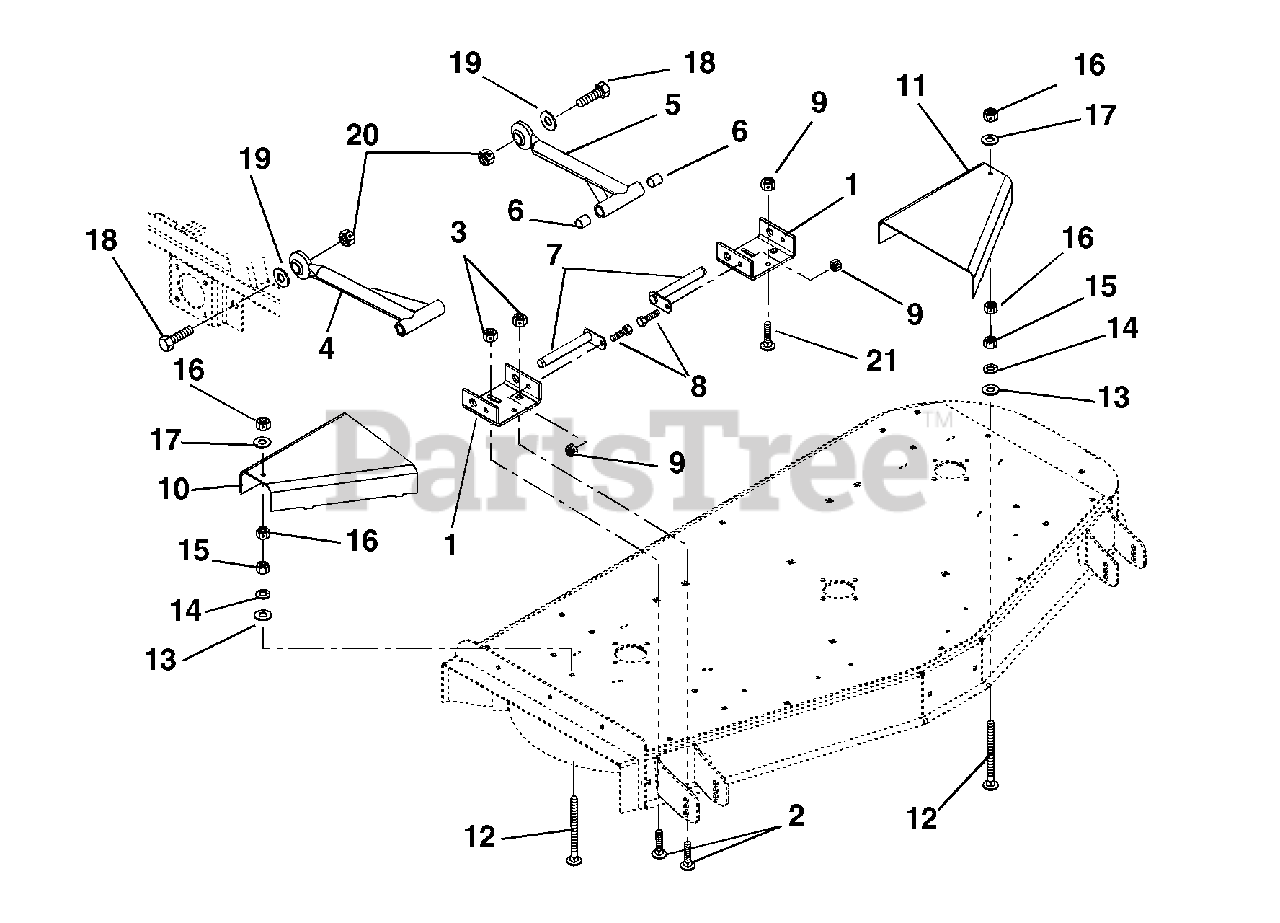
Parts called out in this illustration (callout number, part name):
1	Bracket, Mower Mounting (Rear)
2	Bolt-Round Head Square Neck .50-13 x 1.00 Grade 2
3	Nut-Locking-Center .50-13
4	Assembly, Mower Mounting Arm
5	Weldment-Mower Mounting Arm
6	Bearing .75 x .875 x 1.00
7	Weldment, Mower Mounting Pin
8	Bolt-Hex .38-16 x .75 Grade 5
9	Nut-Locking-Center .38-16
10	Guard, Pulley Right Hand
11	Guard, Pulley Left Hand
12	Bolt-Round Head Square Neck .31-18 x 3.50
13	Washer-Flat-Steel .344 x .688 x .065
14	Washer-Locking .31 x .078
15	Nut-Hex .31-18
16	Nut-Locking-Center .31-18
17	Washer-Flat-Steel .438 x 1.00 x.083
18	Bolt-Hex .875-9 x 2.75 Grade 5
19	Washer-Flat-Steel .875 x 1.50 x .120
20	Nut-Locking-Center .875-9
21	Bolt-Round Head Square Neck .38-16 x 1.00 Grade 5
